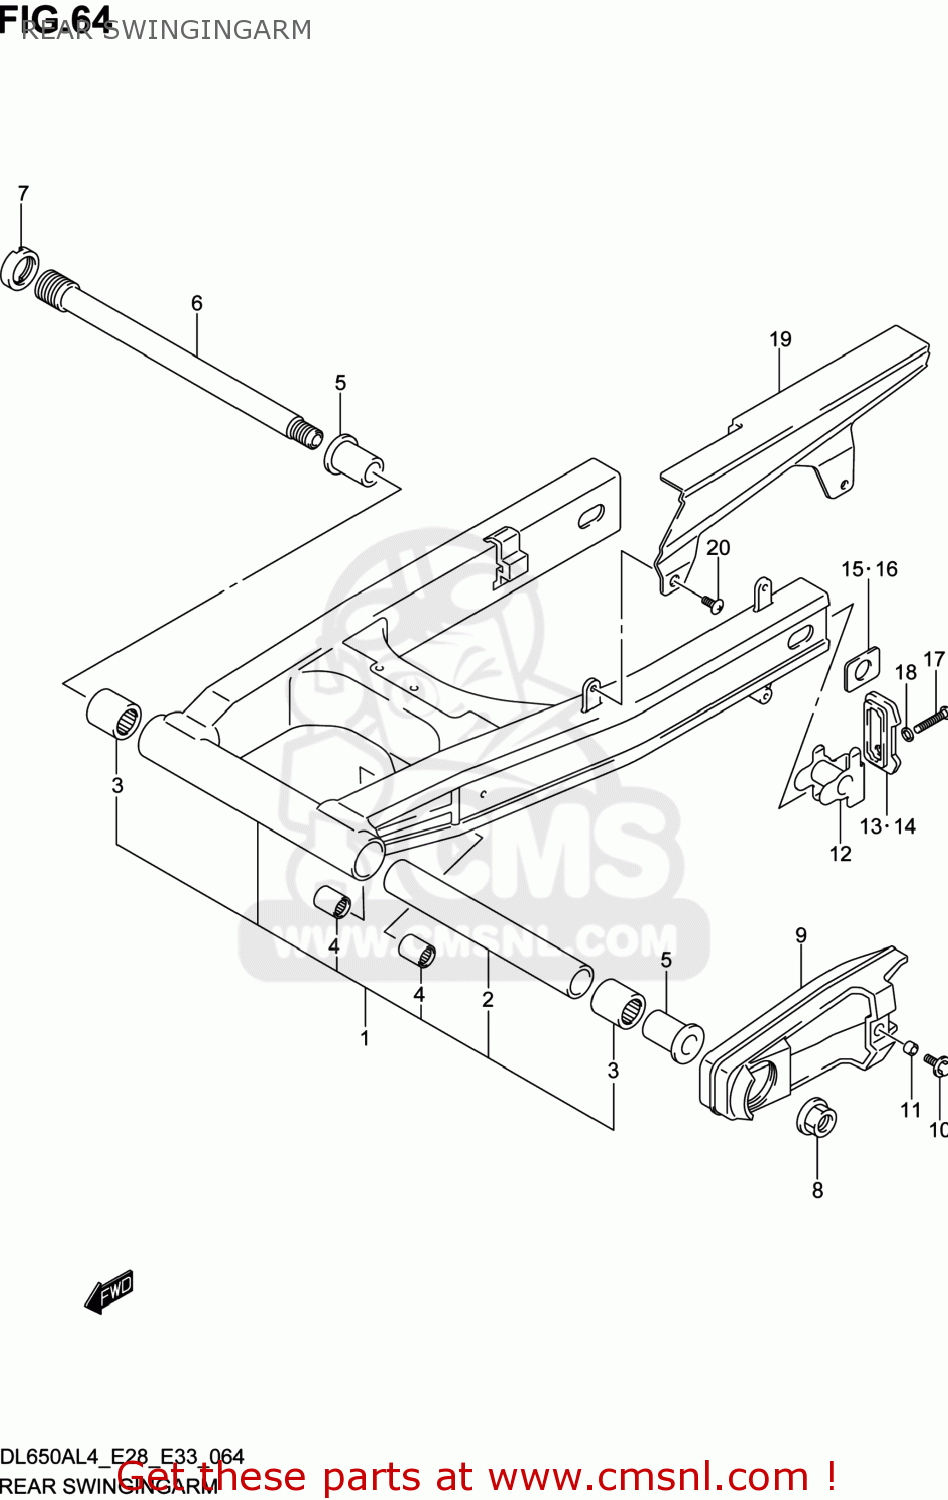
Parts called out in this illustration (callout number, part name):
1	SWINGINGARM ASSY,RR
2	SPACER(20.8X27.2X196.7)
3	BEARING(25X33X35)
4	BEARING(17X24X25)
5	SPACER,RR SWGARM PIVOT BERRING
6	SHAFT,RR SWINGINGARM PIVOT
7	NUT,RR SWGARM PIVOT BOLT
8	NUT
9	BUFFER,CHAIN TOUCH DEFENSE
10	BOLT(6X20)
11	SPACER(6.5X10X7)
12	ADJUSTER,CHAIN
13	PLATE,CHAIN ADJUSTER GUIDE,R
14	PLATE,CHAIN ADJUSTER GUIDE,L
15	WASHER,CHAIN ADJUSTER
16	WASHER,CHAIN ADJUSTER
17	BOLT(8X50)
18	WASHER
19	CASE,CHAIN
20	SCREW(6X16)
